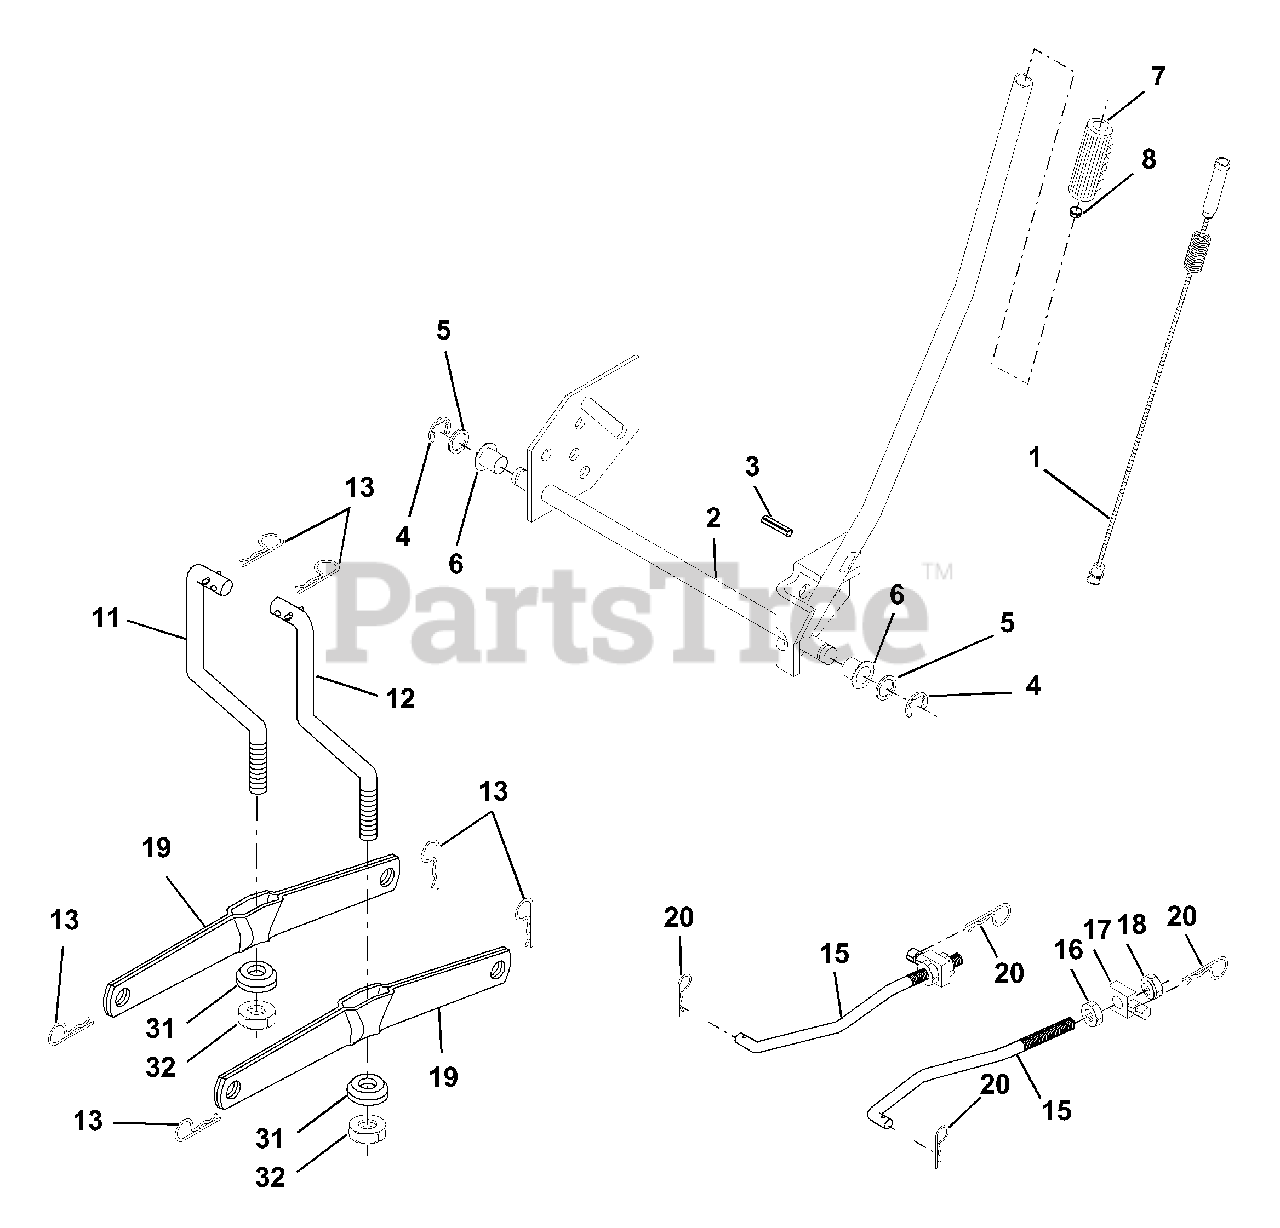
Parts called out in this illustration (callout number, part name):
1	Wire Asm Inner W/plunger LT
2	Shaft Asm Lift
3	Pin Groove
4	E Ring #5133-62
5	Washer PLTD 21/32 X 1 X 21ga
6	Bearing Nylon Blk 629 Id
7	Grip Handle Bicycle
8	Button Plunger Black
11	Link Lift LH
12	Link Lift RH
13	Retainer Spring
15	Link Front
16	Nut Jam Hex 1/2-13 Unc
17	Trunnion Blk Zinc
18	Nut Lock W/Wsh 1/2-13 Unc
19	Arm Suspension Rear
20	Spring, Retainer
31	Bearing Pvt. Lift
32	Nut Crownlock 3/8-24
